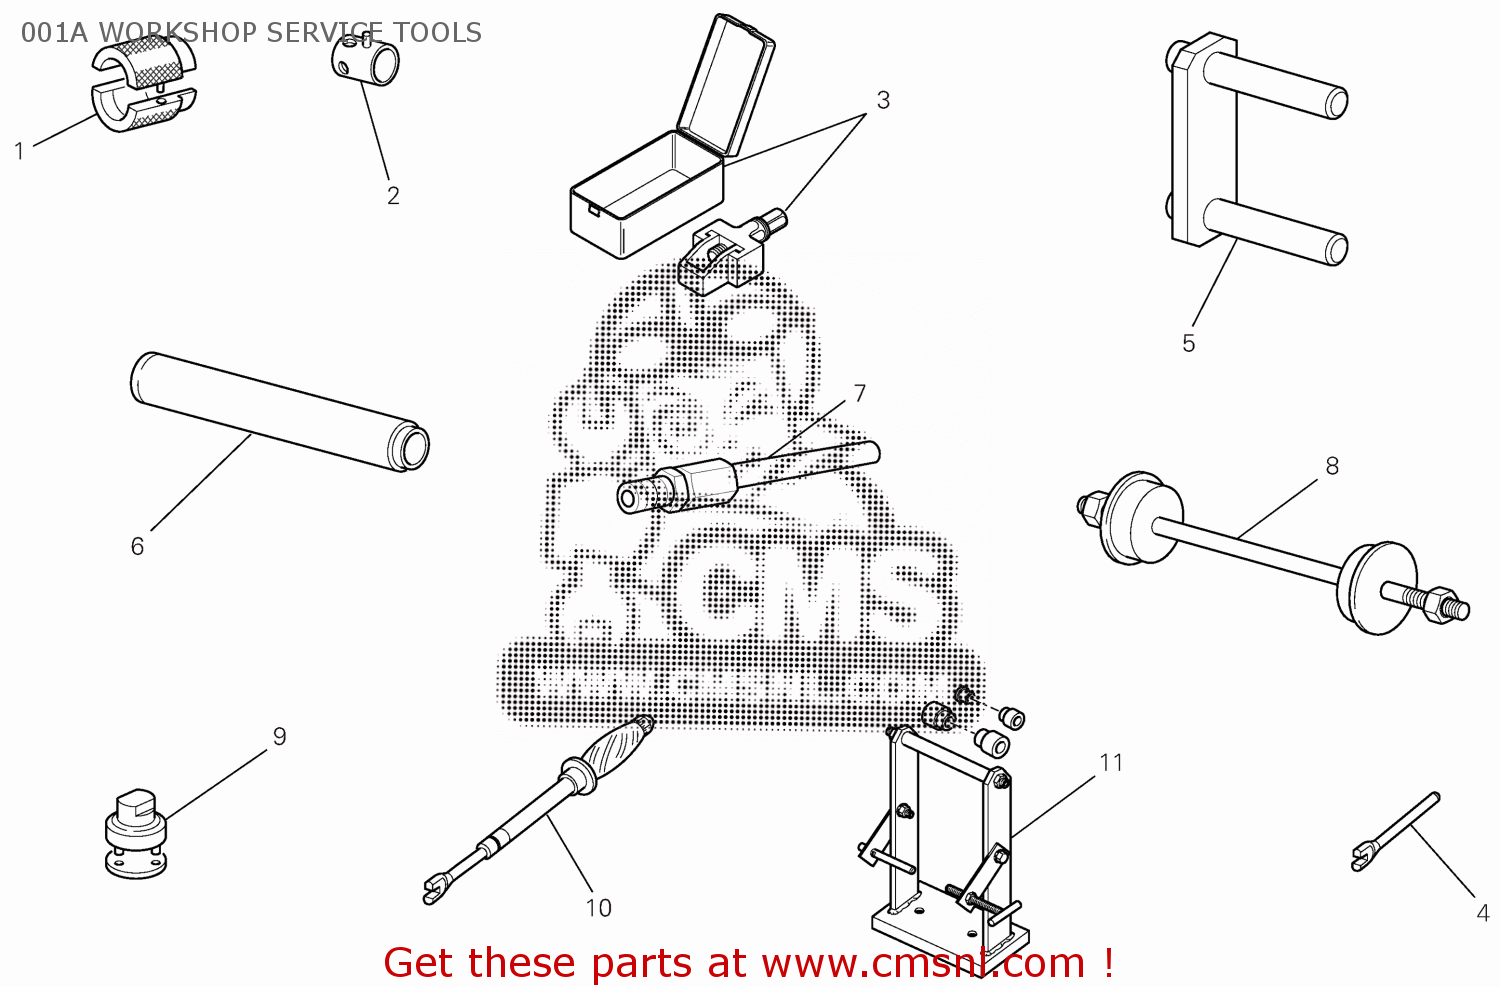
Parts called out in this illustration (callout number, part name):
1	TOOL TO OVERHAUL FORKS
2	WRENCH FOR FRONT WHEEL SPINDLE
3	TOOL FOR ASSEMBLING CHAIN
4	WRENCH NIPPLES TORQUE
5	FRAME/MOTOR SUPPORT
6	DRIVING STOPPER FOR THE HALF BEARING
7	CONNECTOR FOR EXHAUST GAS TAKE-UP POINT
8	TOOL ASSEMBLING STEERING TUBE BEARING
9	SPANNER TO ASSEMBLE THE STEERING SLEEVE
10	WRENCH NIPPLES TIGHTENING
11	TOOL SPOKE WHEELS TRUING
